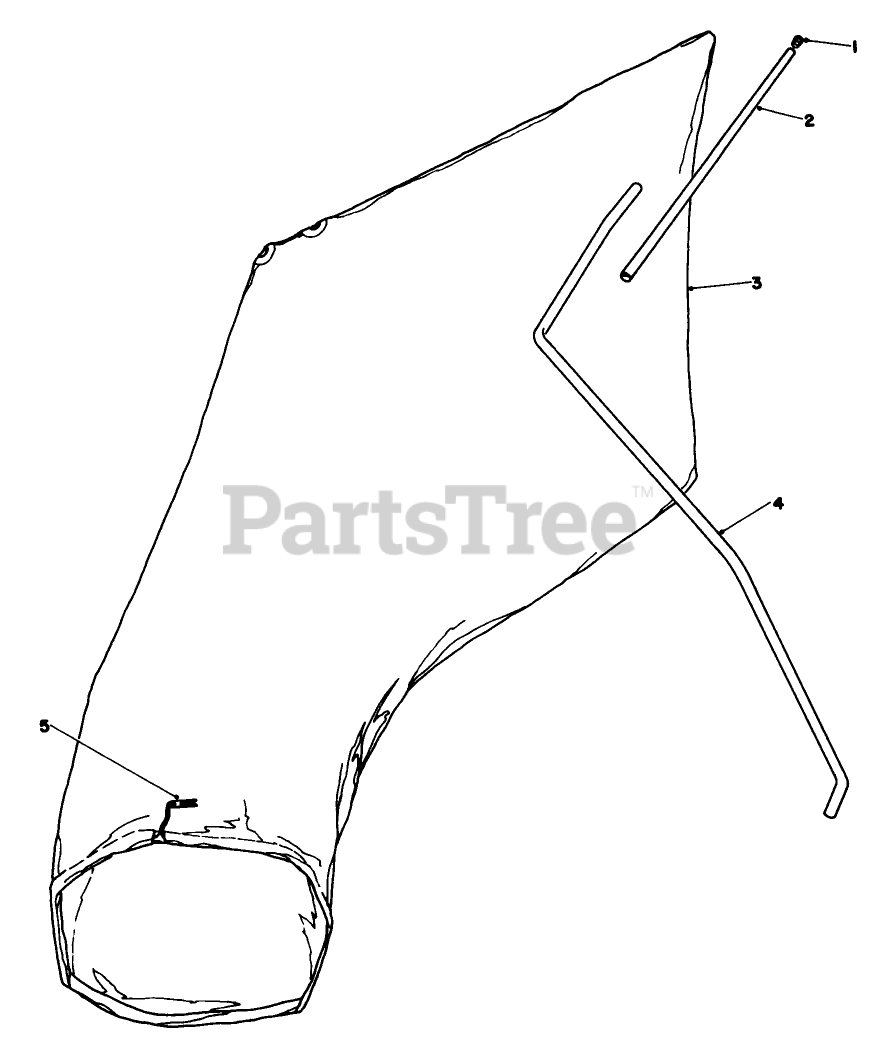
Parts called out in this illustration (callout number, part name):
2	BAG HANGER TUBE
3	Bag (Incl. Ref. #5)
4	Hanger Rod
5	BAG CORD FASTENER
